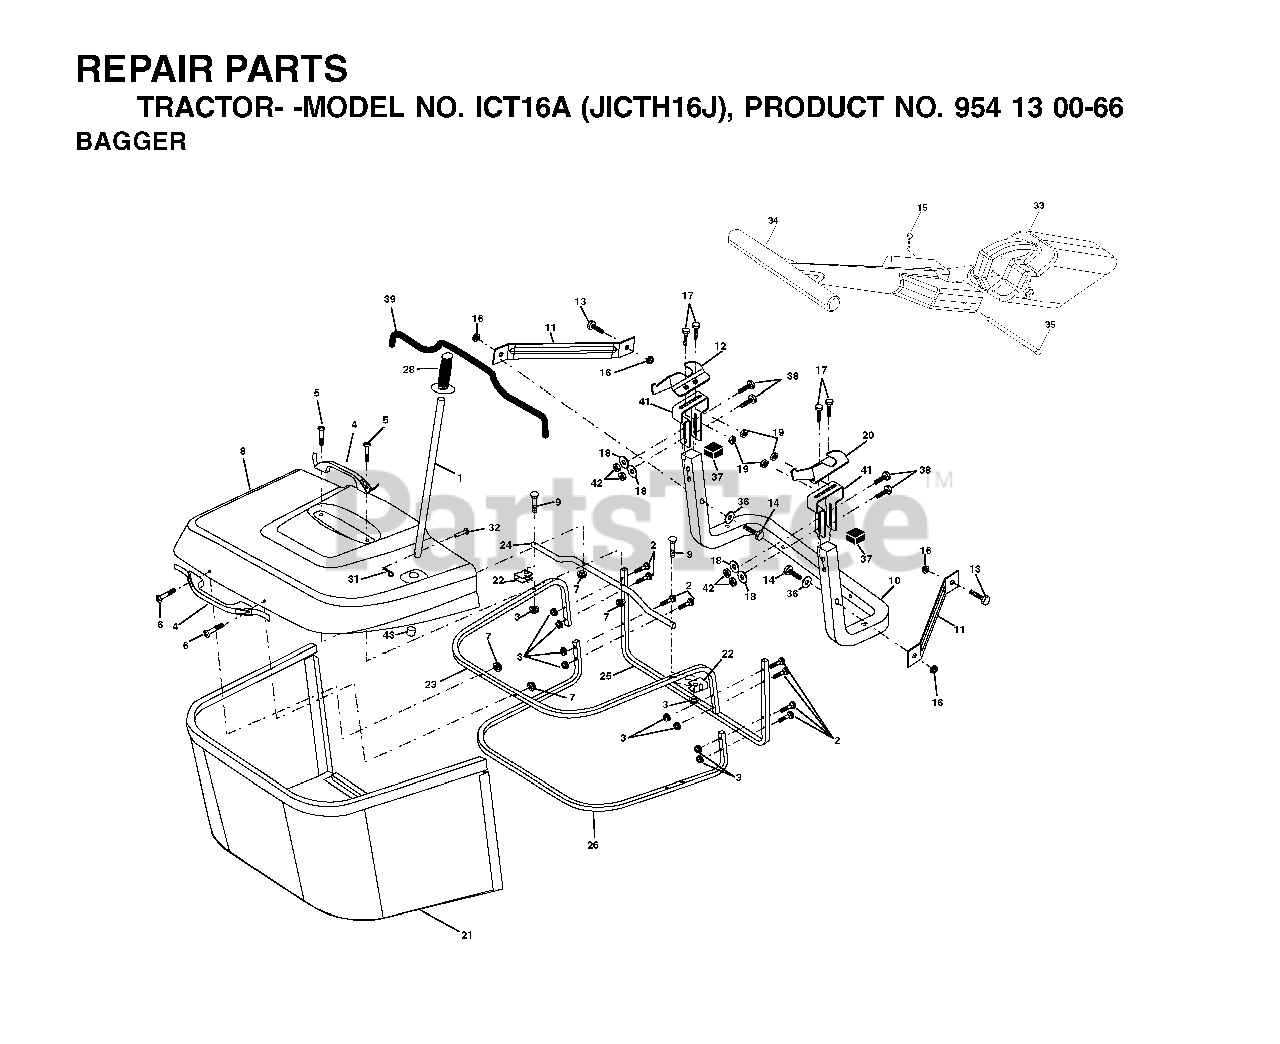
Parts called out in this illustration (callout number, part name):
1	TUBE HANDLE
3	NUT T
5	SCREW.PAN.HEAD
11	BRACKET
14	BOLT-HEX EAK
15	RETAINER-SPRNG RB
16	NUT LOCK FLG 3/8-16 UNC
17	BOLT
18	WASHER M
19	NUT LOCK HEX FLANGE 5/16-18
20	BRACKET
21	GRASS BAG
22	BRACKET
23	TUBE
24	TUBE
26	TUBE
28	GRIP.HANDLE.BLACK
31	RETAINER M
32	RIVET,DRILLED
33	PLUG
35	PIN
36	WASHER
38	BOLT.5/16-18X2.5
41	BRKT, BAGGER
42	NUT.71038.31-18.HEX.NYLOCK
43	PLUG, TUBING END
